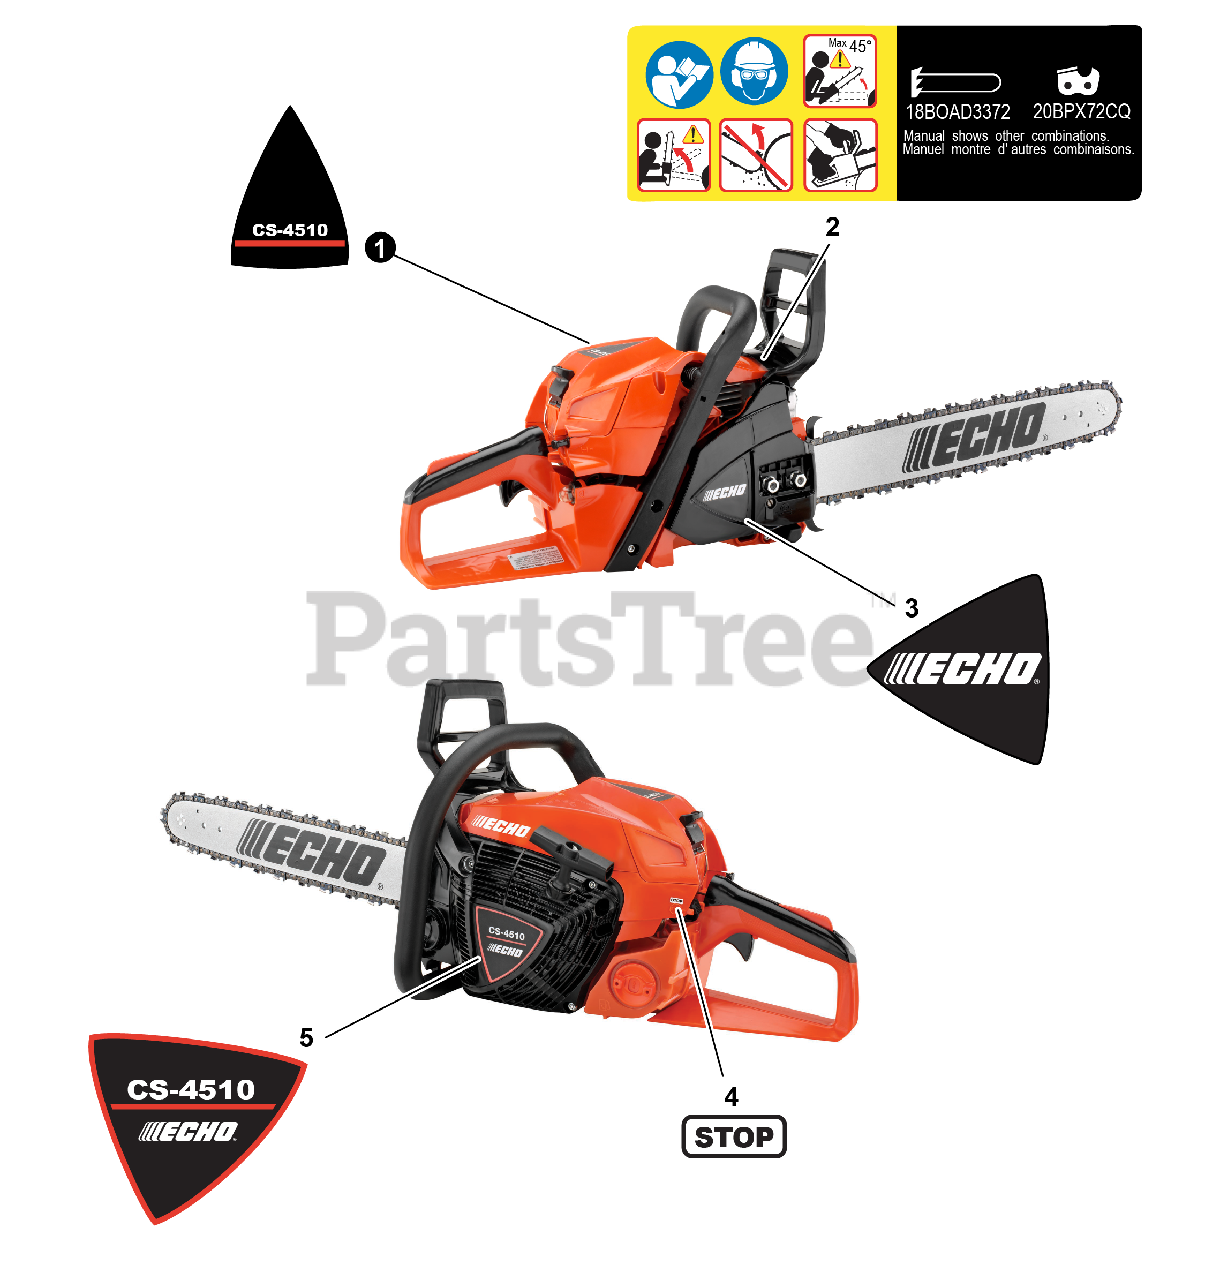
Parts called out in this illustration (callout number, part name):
1	LABEL, MODEL CS-4510
2	LABEL, CAUTION
3	LABEL, ECHO
4	LABEL, STOP
5	LABEL, MODEL CS-4510
